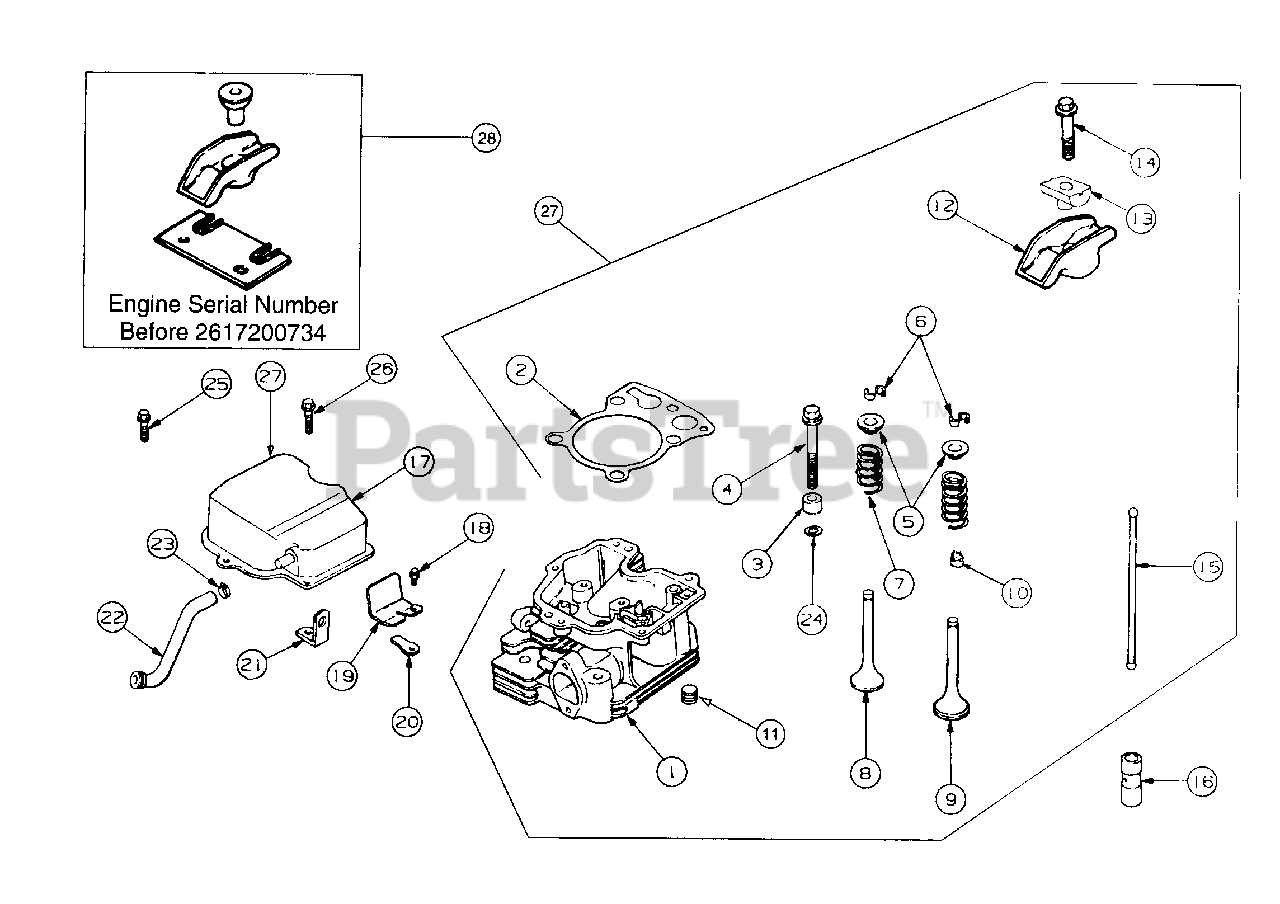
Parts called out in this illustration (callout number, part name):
1	Cylinder Head
2	Gasket, Cylinder Head
3	Spacer, Head Bolt, Exhaust Port
4	Screw, Cylinder Head, M10 x 1.5 x 81
5	Cap, Valve Spring
6	Kit, Retainer
7	Spring, Valve
8	Valve, Exhaust, Std
9	Valve, Intake, Std
10	Seal, Valve Stem
11	Plug, Allen Hd. 1/8" Pipe
13	Pivot, Rocker Arm
14	Screw, Pivot Rocker, M6 x 1.0 x 34
15	Rod Push
16	Lifter, Valve
17	Cover, Valve w/Nipple
18	Screw, Brthr Reed Ret, M5 x .8 x 10
19	Retainer, Breather Reed
20	Reed, Breather
21	Strap, Lifting
22	Hose, Breather
23	Clamp, Hose
24	Washer, Flat
25	Screw,Hex Flange, M6 x 1.0 x 20
26	Screw, Valve Cover, M6 x 1.0 x 25
27	Kit, Cylinder Head
28	Upgrade to Current Rocker Arm Assy
